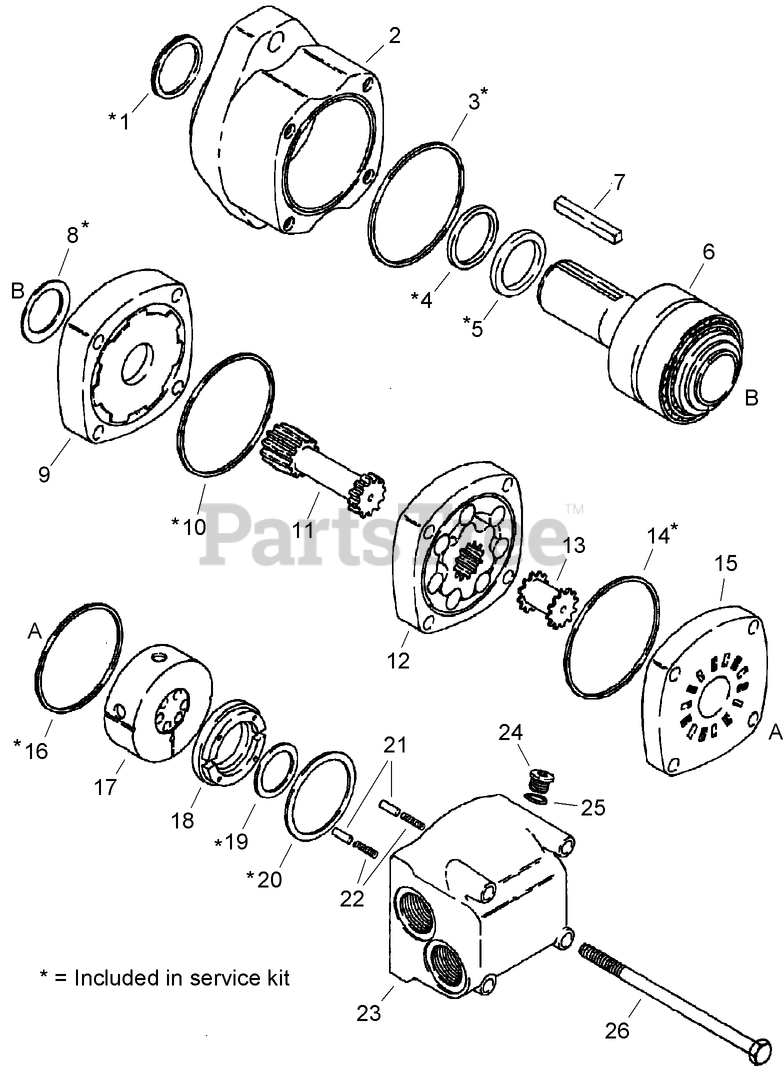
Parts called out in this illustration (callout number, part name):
1	SEAL - Dust
2	HOUSING - Bearing
3	SEAL - 3 inch (76 mm) ID, Bearing Housing
4	RING - Backup, Shaft Seal
5	SEAL-Shaft
6	KEY - Square, Shaft
7	SHAFT AND BEARING ASSEMBLY - Motor (components not serviced separately)
8	SEAL - Shaft, to Wear Plate
9	PLATE - Wear, Motor
10	SEAL - 3 inch (76 mm) ID, Wear Plate
11	SHAFT - Motor Drive
12	GEROTOR ASSEMBLY - Motor
13	DRIVE - Valve
14	SEAL - 3 inch (76 mm) ID, Valve Plate
15	PLATE - Valve
16	SEAL - 3 inch (76 mm) ID, Housing
17	VALVE - Motor
18	PLATE - Balance
19	SEAL - Balance Plate, Inner
20	SEAL - Balance Plate, Outer
21	PIN - Valve Housing
22	SPRING - Pin
23	HOUSING - Motor, Port End (order 188974A1 motor assembly)
24	PLUG-SOC HD
25	O-RING - 23/64 ID x 5/64 inch Wide
26	BOLT - Hex, Special
